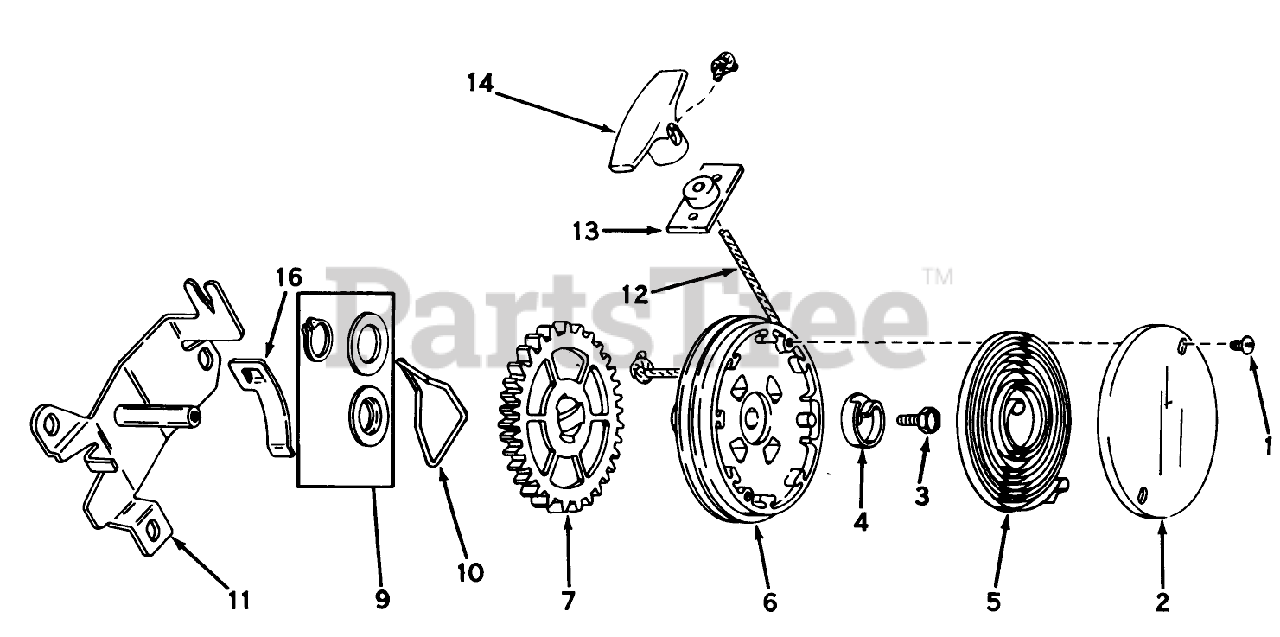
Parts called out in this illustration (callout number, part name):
1	Screw, Cover
2	Cover, Spring
3	Screw
4	Hub Spring
5	Spring, Rewind
6	Pulley Assy. (Incl. No. 9)
9	Kit, Thrust Wash. Snap Rg.
10	Brake
11	Bracket Assy. Mounting
12	Rope, Starter
13	Bracket Assy.
14	Handle-Starter
16	Clip Rope
